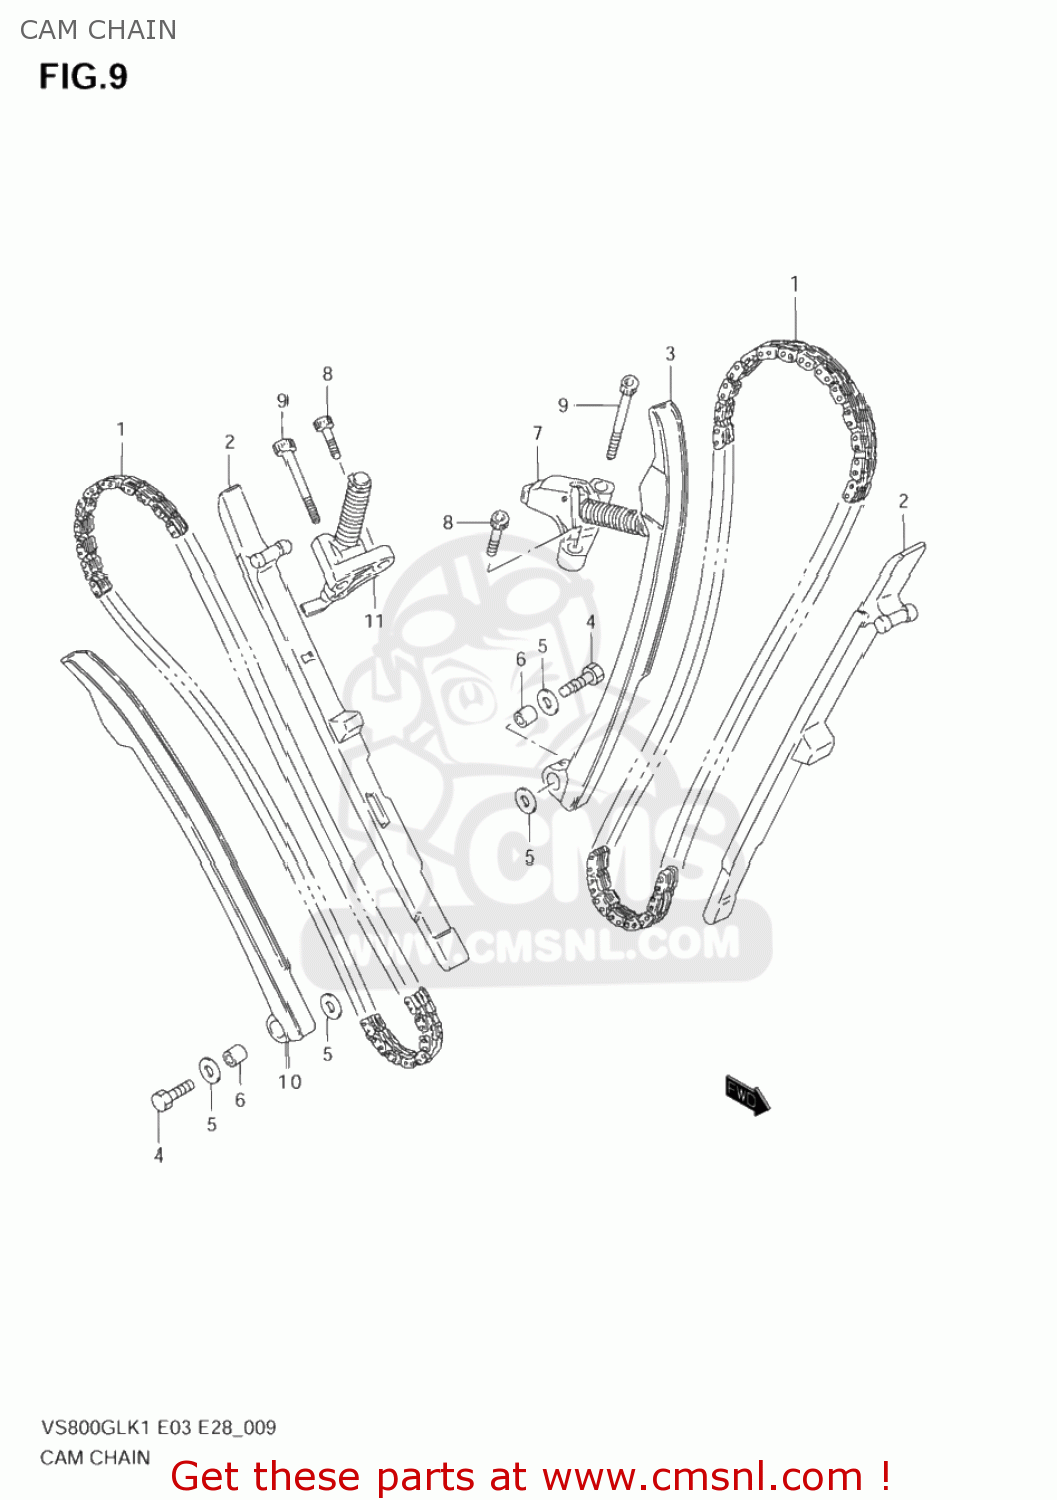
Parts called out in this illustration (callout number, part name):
1	CHAIN COMP,CAMSHAFT DRIVE
2	GUIDE,CAM CHAIN
3	TENSIONER,FR CAM CHAIN
4	BOLT(6X26)
5	WASHER
6	SPACER(6X11X11)
7	ADJUSTER ASSEMBLY,FRONT TENSIONER
8	BOLT,CRKCASE,R
9	BOLT
10	TENSIONER,RR CAM CHAIN
11	ADJUSTER ASSEMBLY,REAR TENSIONER
